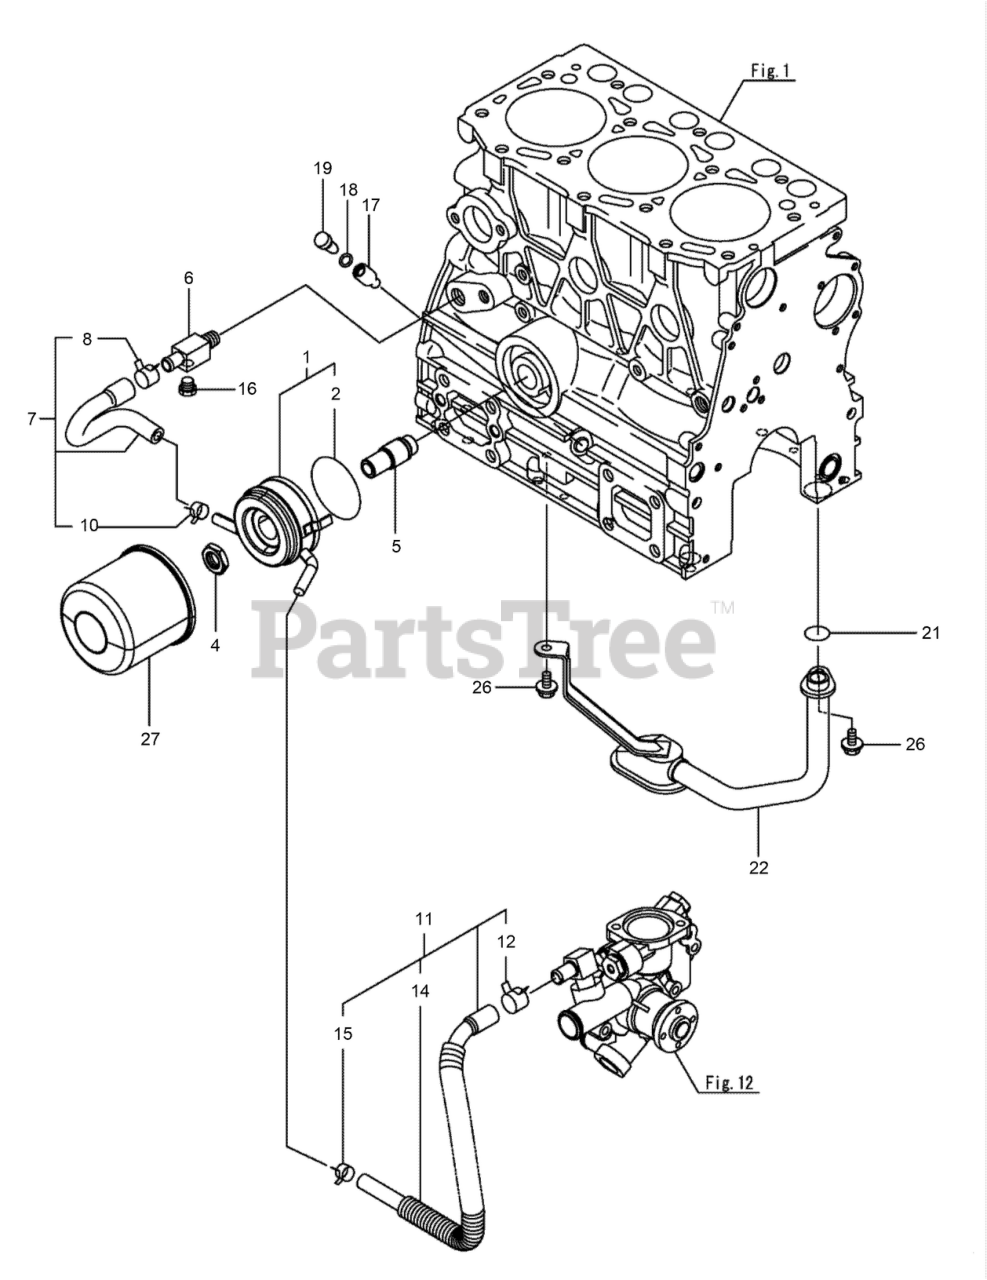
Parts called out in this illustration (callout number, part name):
1	COOLER ASSY, OIL
2	PACKING-OIL COOLER
5	STUD, LO FILTER
7	PIPE ASM-COOLER IN
10	CLAMP-HOSE
11	PIPE ASM
15	CLAMP-HOSE
16	PLUG-DRAIN
17	GUIDE, DIPSTICK
18	O-RING, 4DP10A
19	PLUG-DIPSTICK
21	O-RING
22	OIL INLET PIPE ASM
27	FILTER ENGINE OIL
